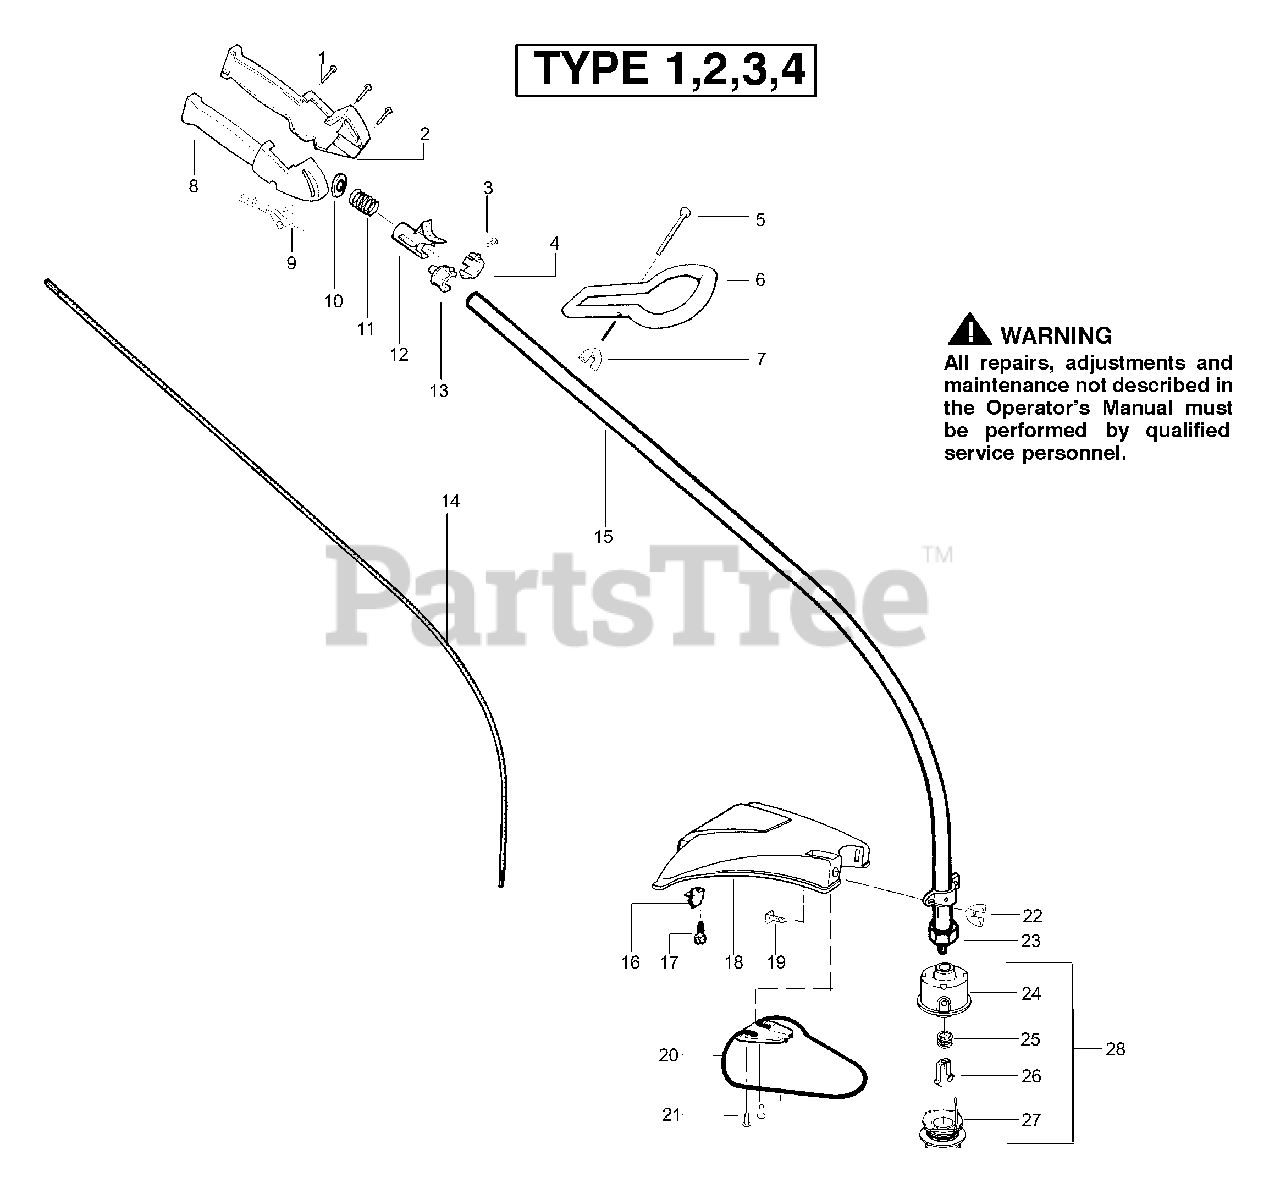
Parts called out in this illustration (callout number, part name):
2	Throttle Hsg. (Left)
3	Screw
4	Locator-left
5	Bolt-Handle
6	Handle-Assist
7	Wingnut
8	Throttle Hsg. (Right)
9	Trigger - Throttle
11	Spring-Compression
12	Actuator
13	Locator-right
14	Flex-Drive Shaft
15	Assy-Drive Shaft Hsg.
16	Line Limiter
17	Screw-Line Limiter
18	Kit-Shield Ass'y.
19	Bolt-Shield
20	Assy-Wire Guard
22	Wingnut
23	Dust Cup
24	Assy-Hub
25	Spring-Return
26	Retainer-Spool
27	Accy-Wound Spool
28	Accy-Cutting Head
